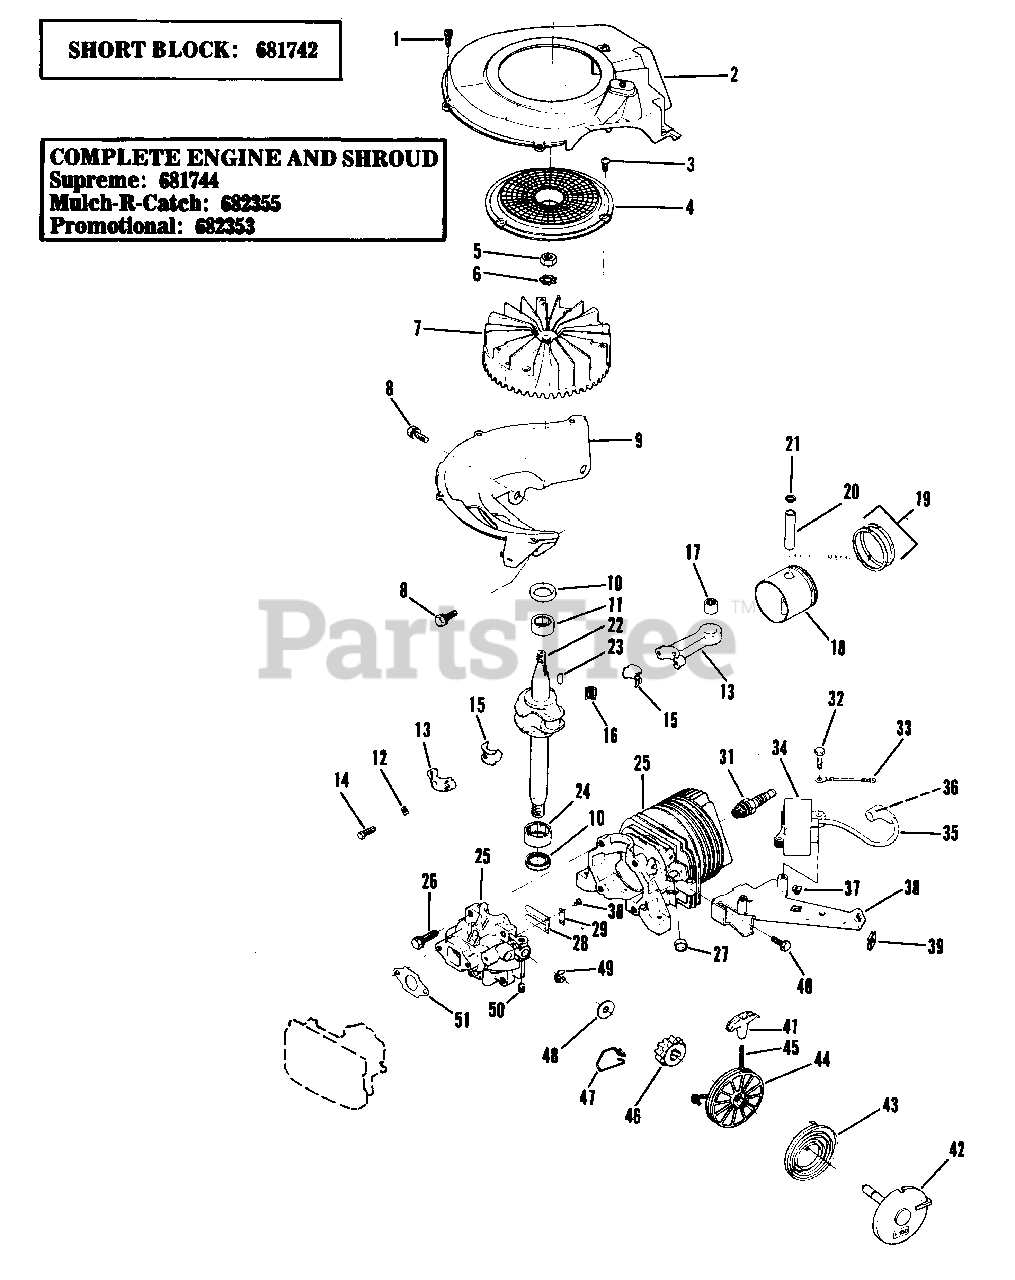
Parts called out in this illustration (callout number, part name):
1	Screw
2	Air Baffle & Eyelet Assembly
3	Screw-Flywheel Screen
4	Screen-Flywheel
5	Nut-Flywheel
6	Lockwasher
7	Flywheel Assembly
8	Screw
9	Base-Shroud
10	Oil Seal
11	Bearing-Upper
12	Lockplate
13	Connecting Rod Assembly
14	Screw
15	Liner-Split
16	Needle Bearing Set
17	Bearing Assembly
18	Piston & Ring Set
19	Ring Set
20	Wrist Pin
21	Retaining Ring
22	Crankshaft
23	Key-Flywheel
24	Bearing-Lower
25	Cylinder & Crankcase Cover Assembly
26	Screw-Cover to Crankcase
27	Plug
28	Reed
29	Plate-Reed Hold Down
30	Screw-Reed to Crankcase Cover
31	Spark Plug
32	Screw-C.D. Mounting
33	Lead Assembly-Ignition
34	C.D. Ignition Module & Lead Assembly
35	High Tension Lead
36	Spring Terminal
37	Grommet-C.D. Bracket
38	Bracket-C.D. Mounting
39	Clip-"U"
40	Screw
41	Handle-Starter
42	Cup & Pin Assembly
43	Spring
44	Pulley
45	Rope
46	Pinion
47	Spring-Drag
48	Washer
49	Retainer
50	Set Screw-Starter Assembly
51	Gasket-Carburetor to Crankcase Cover
